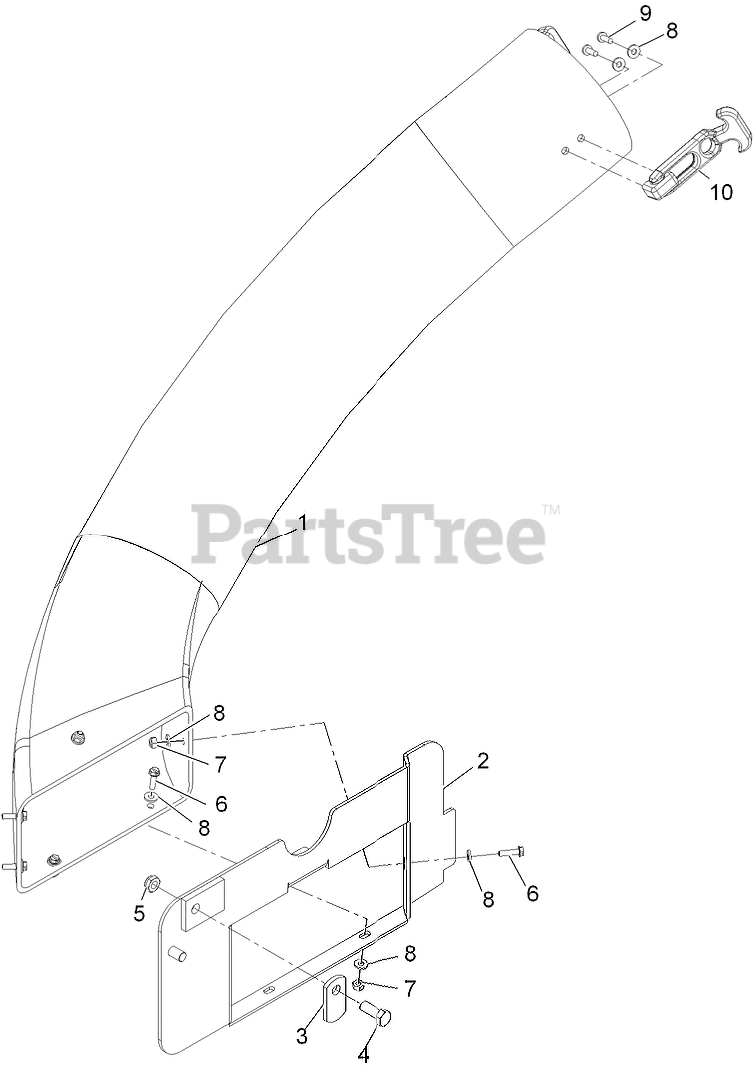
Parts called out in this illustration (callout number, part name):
1	BOOT-LOWER
2	BOOT FRAME ASM
3	LATCH-CATCHER, GRASS
4	SCREW-HH
6	SCREW-HWH
7	NUT-LOCK, NI
8	WASHER-FLAT
9	SCREW-PPH
10	LATCH-RUBBER
